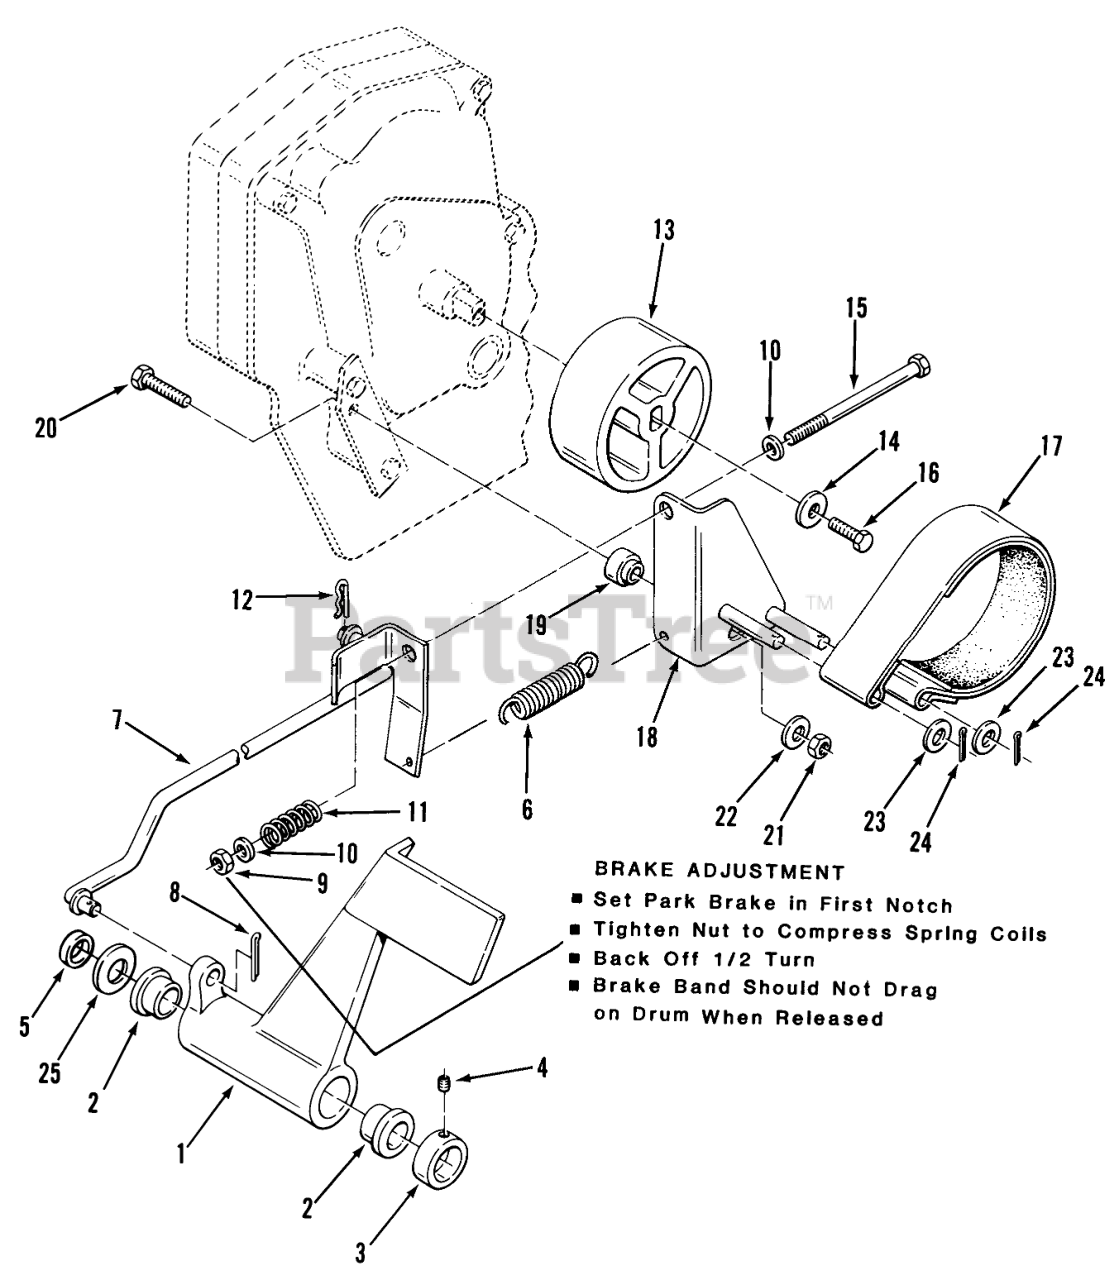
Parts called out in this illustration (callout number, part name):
1	PEDAL R
2	BUSHING
3	Collar
4	SCREW-SET
5	Spacer
6	SPRING
7	ASY BRAK RD WAR
9	NUT
10	Washer
11	SPRING-COMPRESSION
13	DRUM-BRAKE
14	WASHER
15	BOLT
16	BOLT
17	ASSY-BRAKE BAND
18	Brake Pivot Arm
19	BUSHING-BRAKE PIVOT
20	BOLT
21	Nut
22	Washer
23	Washer
24	Cotter Pin
25	WASHER
